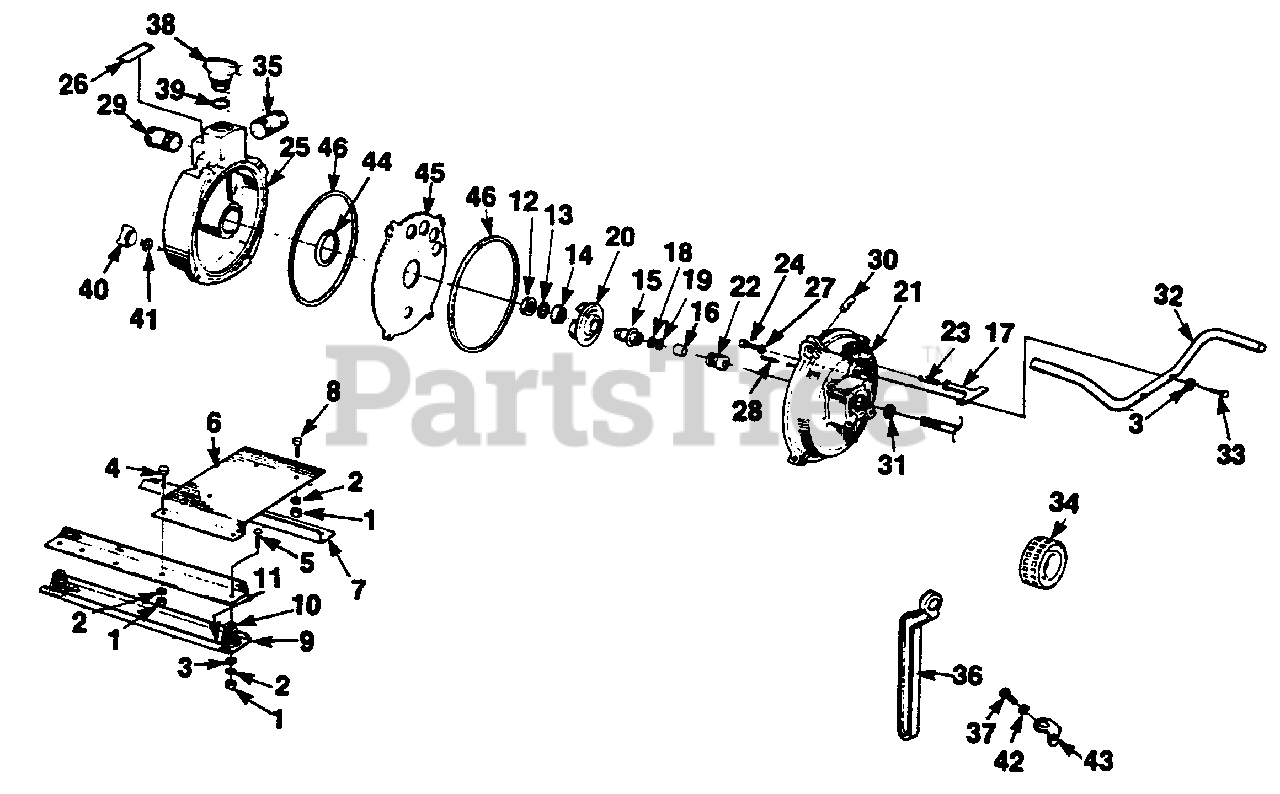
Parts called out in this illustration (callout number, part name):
1	NUT-Hex (5/16-18)
2	WASHER-Lock (5/16)
3	WASHER-Flat (5/16
4	SCREW-Hex hd. (5/16-18 x 3/4")
5	SCREW-Hex hd. (5/16-18 x 1")
6	ENGINE-Support
7	ANGLE-Base
8	SCREW-Cap hex hd. (5/16-18 x 1 1/2")
9	SKID ASSEMBLY
10	SPRING
12	NUT-Impeller
14	BUSHING-Impeller
15	HUB-Impeller
16	SPACER-Crankshaft
17	HANDLE-Disconnect
18	SHIM (.010")
19	SHIM (.015")
20	IMPELLER-Pump
21	WASHER-Sealing
22	SEAL-Shaft
23	STUD-Handle
24	SCREW-Mach. hex hd. (5/16-24 x 2 1/4")
25	HOUSING-End
26	DECAL-Fill pump
27	WASHER-Sealing
28	PIN-Coiled spring
29	NIPPLE-(2" x 2")
30	PIVOT-Handle
31	SLINGER
32	HANDLE-Carry (2")
33	SCREW-Cap hex hd.
34	STRAINER-Suction hose
35	NIPPLE-(2" x 3 1/2)
36	WRENCH
37	SCREW-Cap hex hd.
38	PLUG-Wing
40	PLUG-Drain
42	WASHER-Flat (1/4")
43	HOLDER-Spanner wrench
44	GASKET-Small
45	PLATE-Wear
46	GASKET-Large
